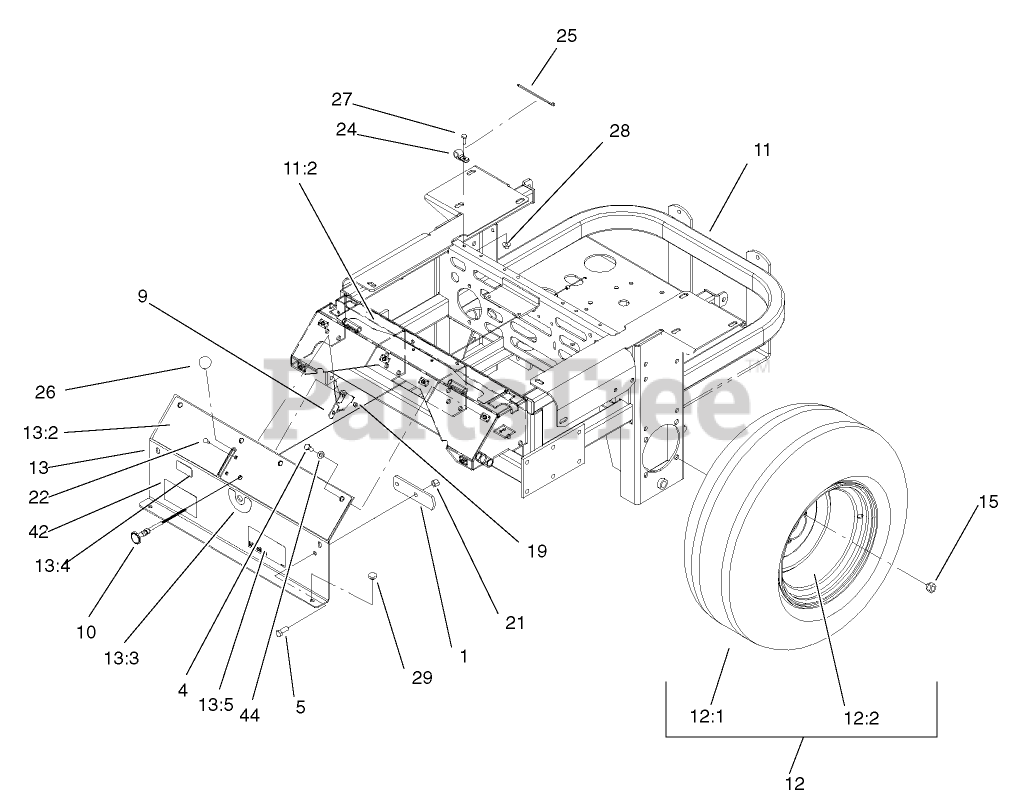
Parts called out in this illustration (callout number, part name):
1	STOP-BRAKE, PARK
4	SCREW-HH
5	SCREW-HH
9	THROTTLE CABLE ASM
10	CONTROL-CHOKE
11	Main Frame ASM
11:2	DECAL-CONSOLE, TOP
12	WHEEL AND TIRE ASM
12:2	WHEEL RIM
13	CONSOLE ASM
13:2	DECAL-PANEL, CONTROL
13:3	DECAL-VALVE, FUEL
13:4	DECAL-PROTECTION, EAR
13:5	DECAL-MOBIL 1
15	NUT-LUG
19	NUT-LOCK, NI
21	NUT-LOCK, NI
22	BOLT-CARR
24	CLIP-LOOM
25	TIE-PLASTIC
26	KNOB-BALL
27	SCREW-HH
28	NUT-HF
29	BUMPER
42	DECAL-TORO, Z255
44	WASHER-PLAIN
